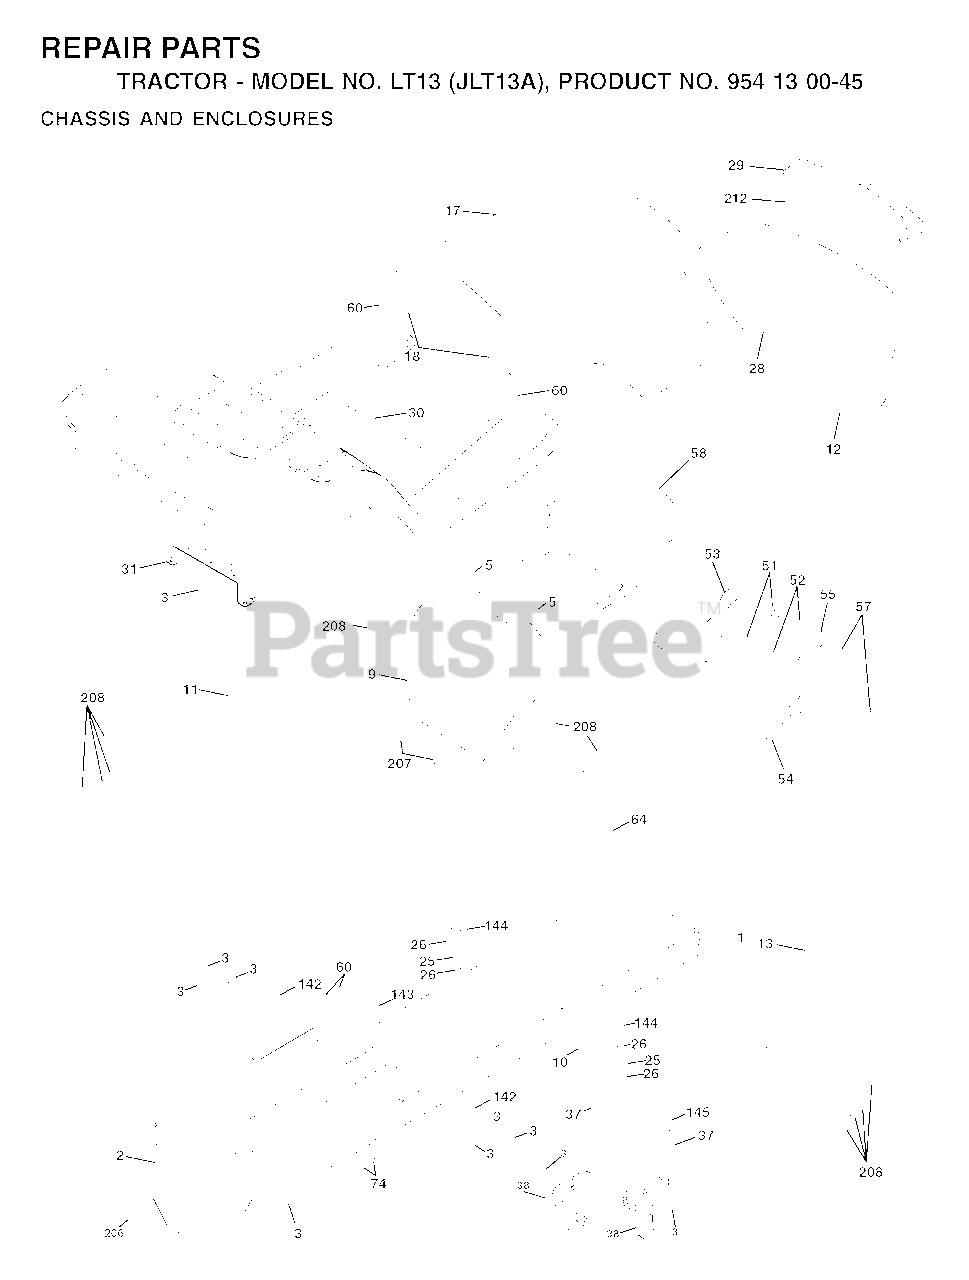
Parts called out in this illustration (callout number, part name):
2	DRAWBAR
3	SCREW 3/8-16X3/4
5	BUMPER.RUBBER.HOOD
10	BOLT D
11	PANEL DASH LH
13	DASH PANEL ASM.
18	BUMPER HOOD T
25	WASHER
26	NUT
38	BRACKET
51	LOCKNUT
57	BOLT
58	AIR DUCT P/L/LT
64	DASH LOWER
74	LOCKNUT
142	PLATE
143	BRACKET, SWAY BAR
144	BRACKET FOOTREST
145	ROD PIVOT CHASSIS/HOOD
206	SHOULDER BOLT 5/16-18TT
207	SCREW, 5/16-18 X 1/2
208	SCREW 3/8-16X1/2
